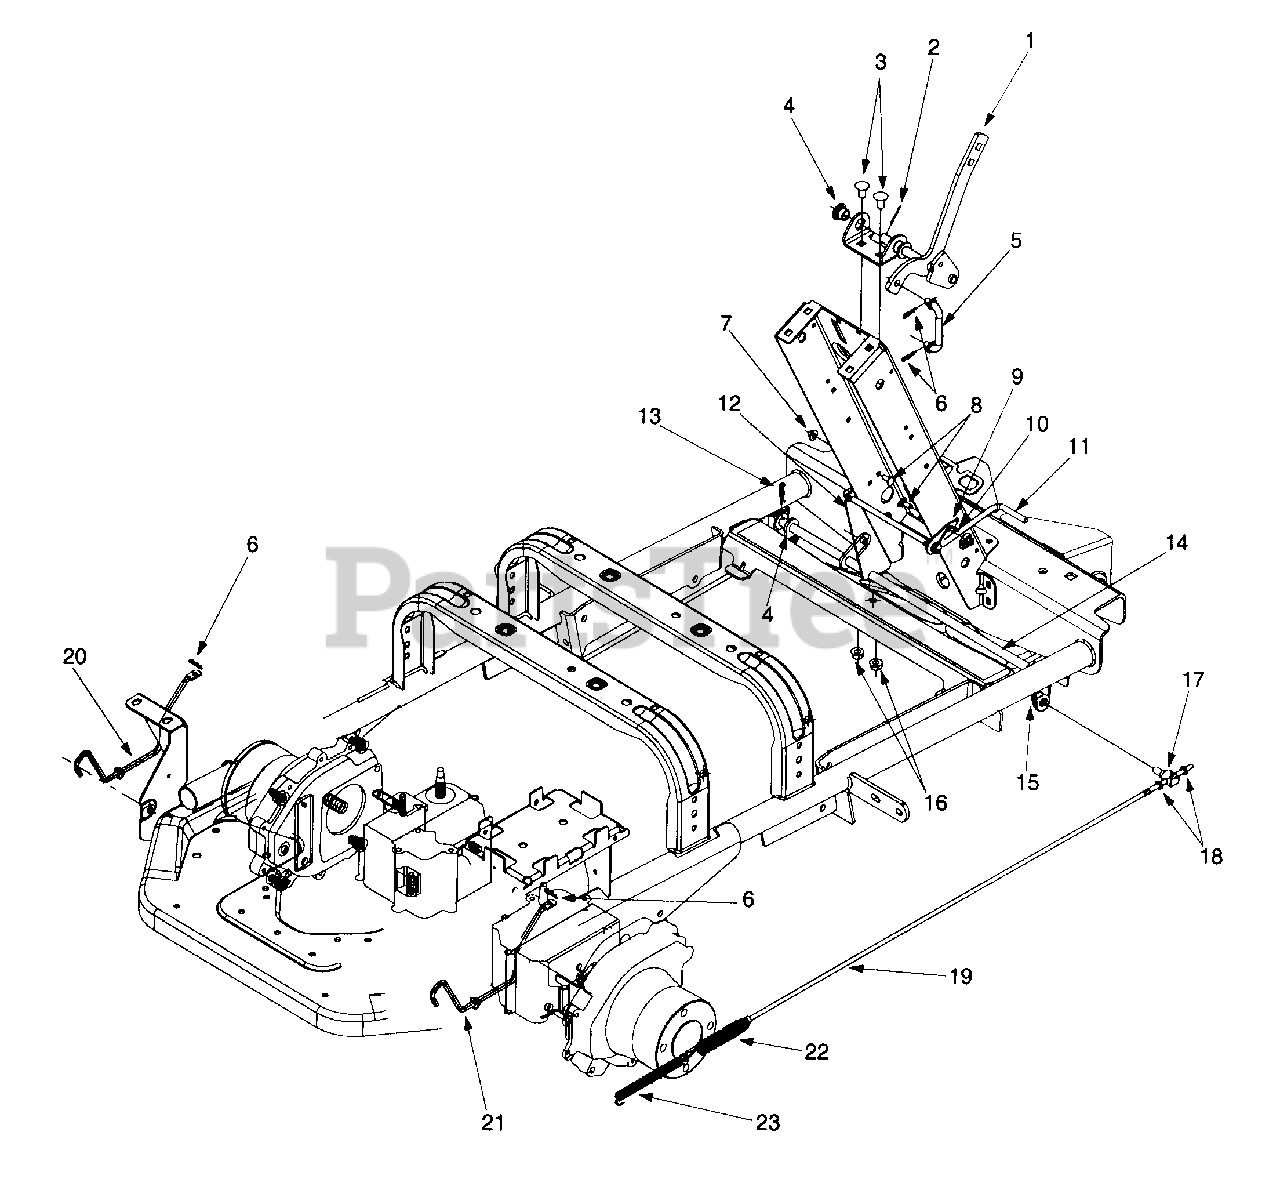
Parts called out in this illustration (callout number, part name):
1	Parking Brake Shift Ass'y
3	Carriage Bolt 3/8-16 x .75
4	Hex Flange Bearing .506 ID x .590
5	Connecting Brake Rod
7	Hex Flange Lock Nut 1/4-20
8	Carriage Screw 1/4-20 x .62
9	Retaining Rod Bracket
10	Torsion Spring 5/16
11	Parking Brake Retaining Rod
12	Support Plate
14	Brake Rod Ass'y
15	Flat Washer .385 ID x 1.0 OD
16	Flange Lock Nut 3/8-16
18	Jam Nut 1/4-28
20	Release Pump Rod LH
21	Release Pump Rod RH
22	Extension Spring
23	Extension Spring
